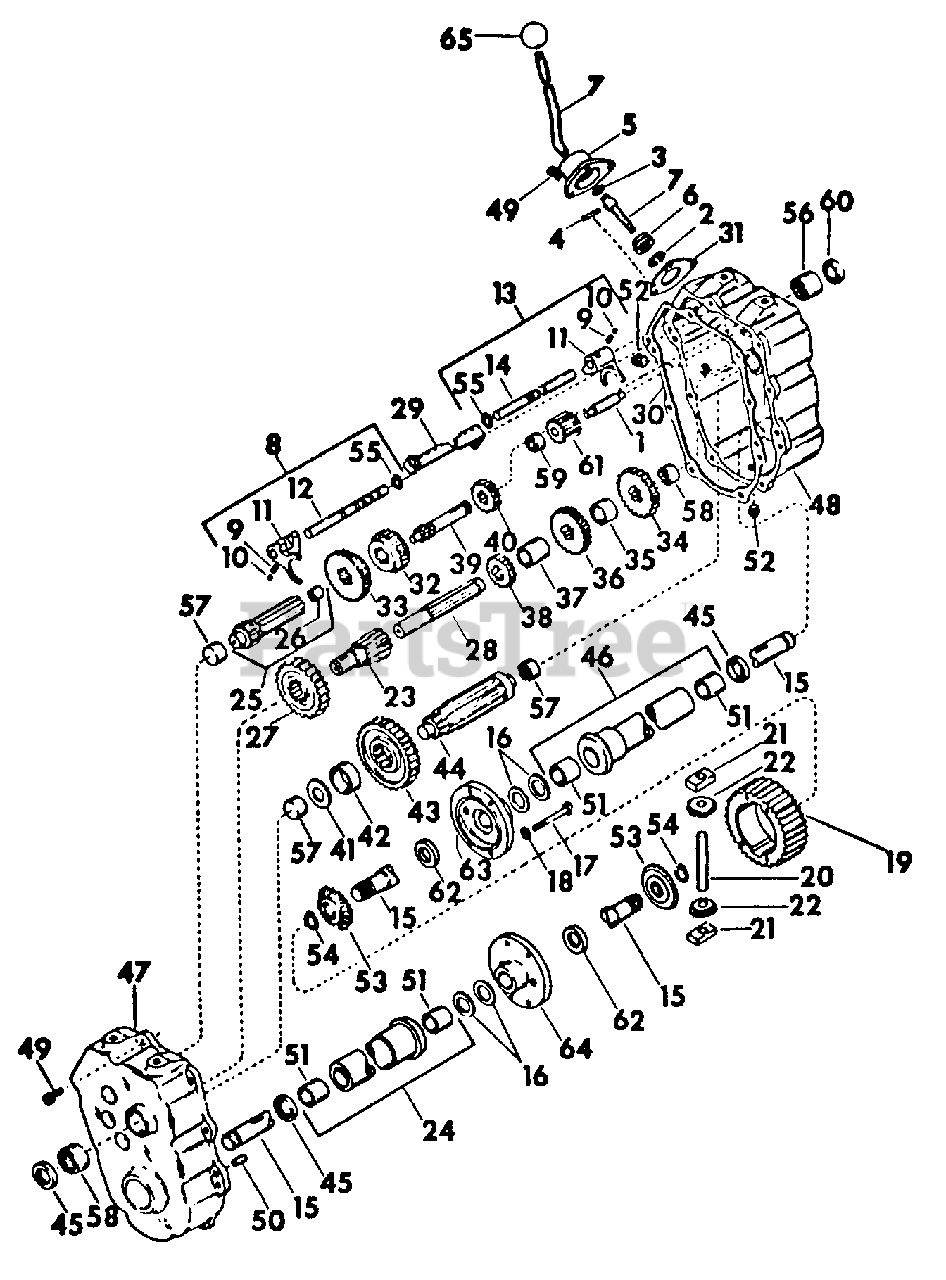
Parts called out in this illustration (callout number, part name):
1	Shaft, Reverse Idler
2	Ring, Snap
4	Pin, Drive
5	Housing, Shift Lever
6	Keeper, Shift Lever
7	Lever, Shift
8	Rod Assy, Shift
10	Ball, 3/16 Cr Stl
11	Fork, Shifter
12	Rod, Shifter
13	Rod Assy, Shift
14	Rod, Shifter
16	Washer, Thrust
17	Screw, 1/4-20 X 2-1/4 Phc Hex Hd Cap
18	Washer, 1/4 Znd Reg Lock
20	Pin, Drive
21	Block, Drive
22	Pinion, Bevel -14T
23	Shaft, Idler Pinion & Bushing
24	Housing w/Bushing, LH
25	Shaft & Bearing, Shifter
26	Bearing, Needle
27	Gear, Idler
28	Shaft, Idler
29	Stop, Shifter
30	Gasket, Case to Cover
31	Gasket, Shift Lever Housing
32	Gear, Shifting -20T
33	Gear, Shifting -26T
34	Gear, Spur -26T
36	Gear, Spur -22T
38	Gear, Spur -16T
39	Shaft, Input
40	Gear, Input Shaft Spur -16T
43	Gear, Output -36T
44	Shaft, Output
46	Housing w/Bushing, RH
47	Cover w/Brgs, Transaxle
48	Case w/Brgs, Transaxle
49	Screw, 1/4-20 X 3/4 Znd Hex Hd Soc Hd Cap
50	Pin, 5/16 X 3/4 Dowel
52	Plug, 3/8-18 Automotive Sq Hd Pipe
53	Kit, Bevel Gear
54	Ring, Retaining
55	Ring, Retaining
56	Bearing, Roller
57	Bearing, Needle
58	Bearing, Needle
59	Spacer, Reverse Idler
60	Seal, Oil
61	Idler, Reverse -12T
63	Carrier, Differential
64	Carrier, Differential
65	Knob, Shifter
